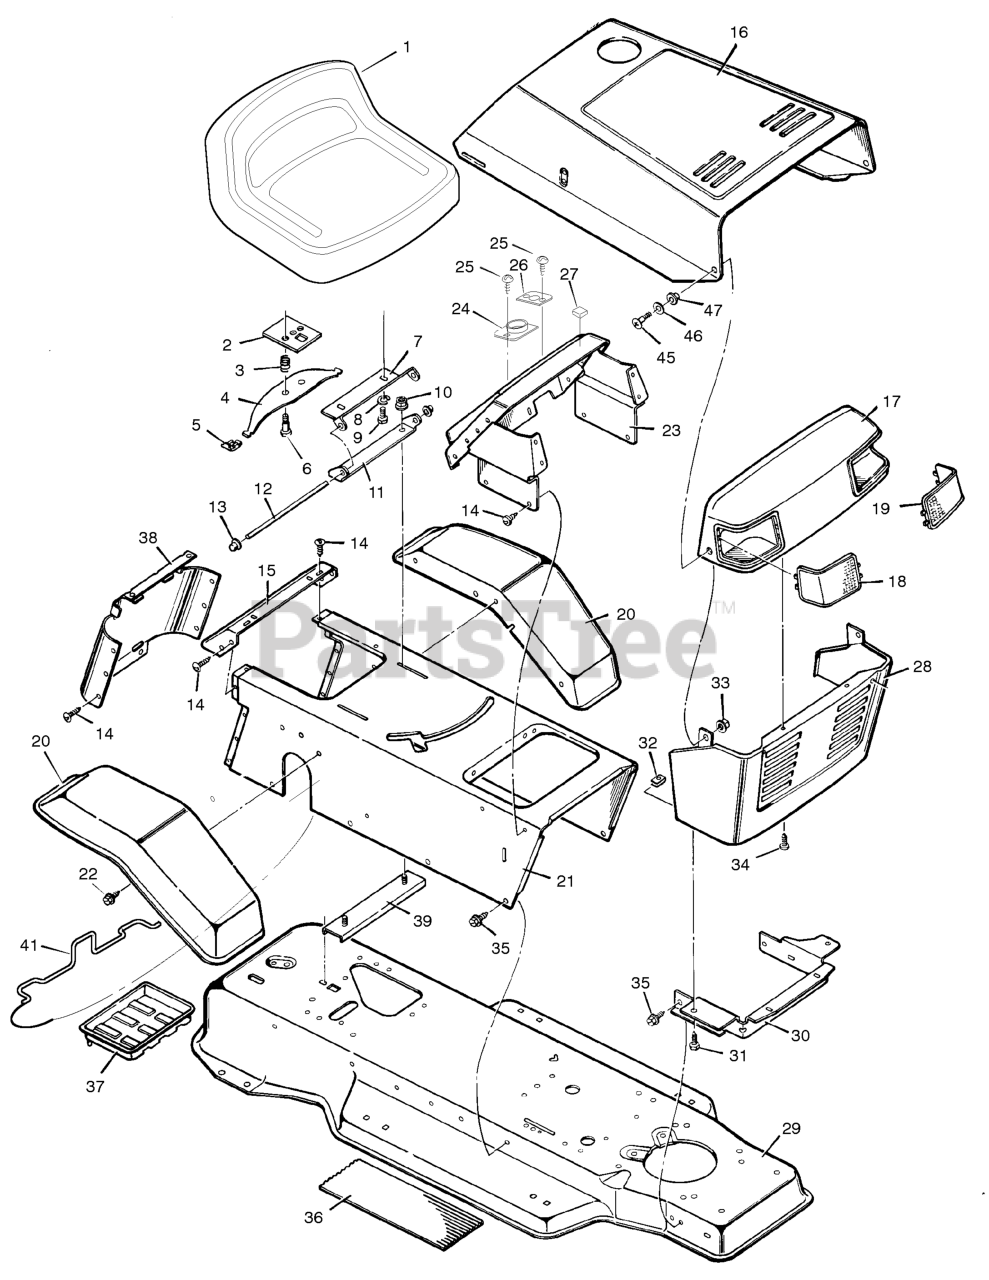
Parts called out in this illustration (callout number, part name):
2	Plate Assembly, Switch
3	Spring, Compression
4	Spring, Seat
5	Glide, Spring
6	Bolt, Shoulder
7	Support, Seat
8	Lockwasher
9	Bolt, Hex
10	Locknut, Flange
11	Bracket, Pivot
12	Rod, Pivot
13	Cap, Push On
14	Screw, Tap
15	Fender, Apron
17	Grille, Upper
18	Lens, Right
19	Lens, Left
21	Console Assembly
23	Dash Panel
24	Bearing, Steering
26	Bearing
27	Bumper
28	Grill, Lower
29	Frame Assembly
30	Support, Grill
33	Locknut, Flange
34	Fastener, Plastic
37	Tray, Battery
38	Cap, Console
39	Channel Assembly
41	Clamp, Battery
45	Bolt, Shoulder
46	Washer, Rubber
47	Eyelet
